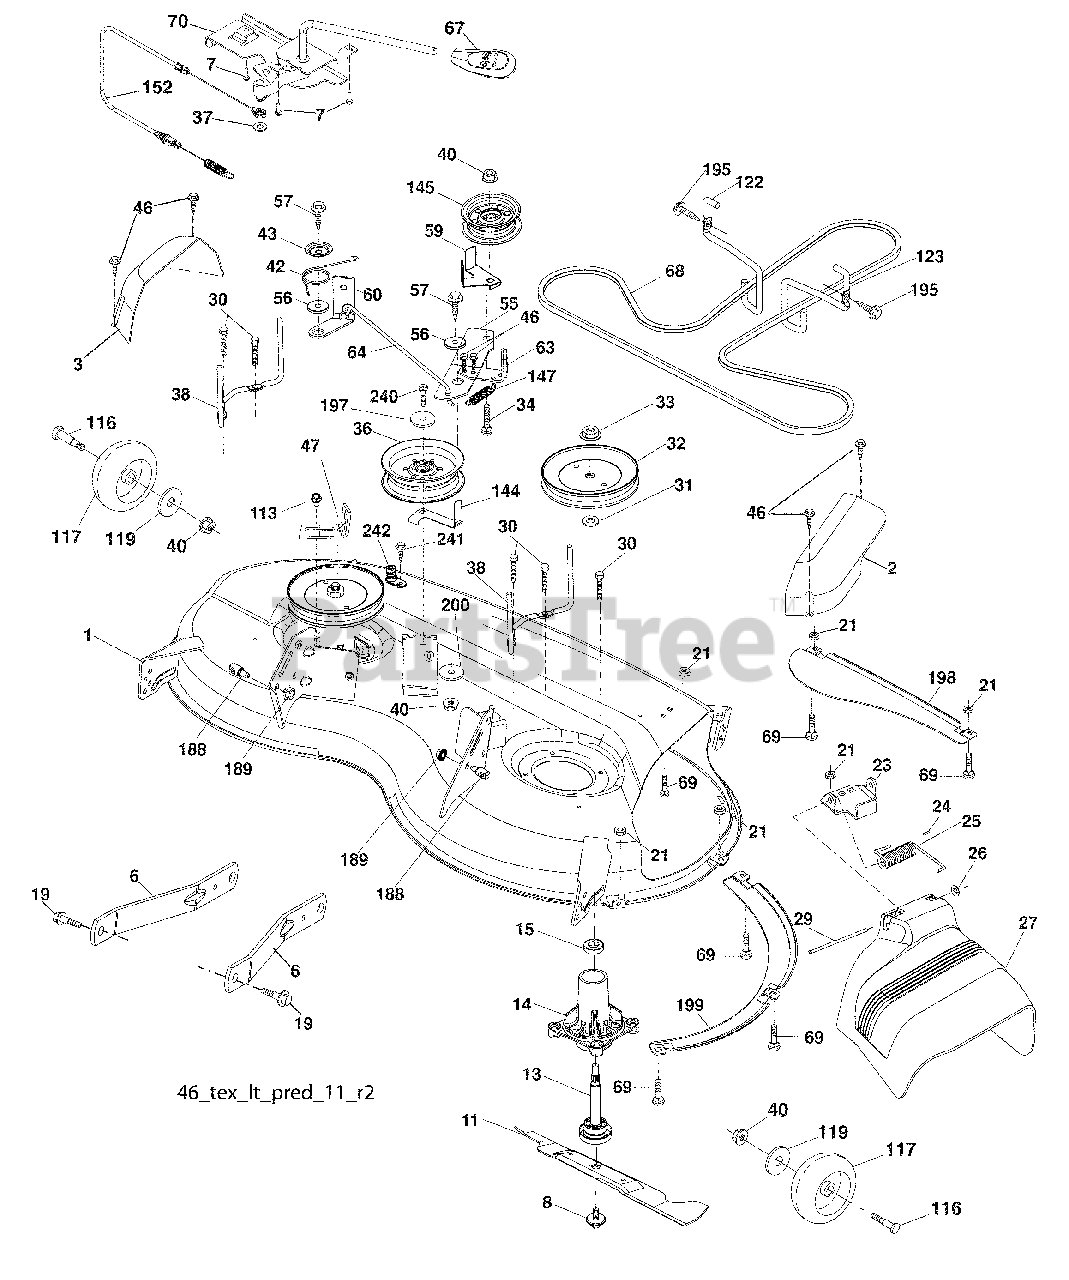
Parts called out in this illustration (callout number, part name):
1	Mower Housing
2	Cover Mandrel RH
3	Cover Mandrel LH
6	Arm Suspension
7	Screw # 10 x 0.750
8	Bolt/Washer asm 7/16-20 unf
11	Blade Mower Hi Lift
13	Shaft Assembly, Mandrel
14	Housing, Mandrel
15	Bearing, Ball, Mandrel
19	Bolt, Shoulder
21	Nut
23	Bracket, Deflector
24	Cap, Sleeve
25	Spring, Torsion, Deflector
27	Shield, Deflector
29	Rod, Hinge
30	Screw Thdrol Rolling Wsh Hd
31	Washer, Spacer
32	Pulley, Mandrel
33	Nut, Toplock, Flanged
34	Bolt Carr Sh. 3/8-16 x 1-1/2 Gr. 5
36	Pulley, Idler, Flat
37	Washer 13/32 x 13/16 x 16 Ga.
38	Keeper Belt LH Mandrel
40	Nut, Lock Flg. 3/8-16 unc
42	Spring Torsion Brake
43	Spring Torsion Retainer
47	Bracket Clutch Cable
55	Arm, Idler
56	Spacer, Retainer
57	Screw Hexwsh Thd 3/8-16 x 1
59	Guard, Tuv Idler (94)
60	Arm Brake Mower LH
63	Arm Brake Mower
64	Linkage Brake
67	Handle, Clutch Cable
68	V-Belt
69	Bolt
70	Clutch Asm. Cable
113	Screw 5/16-18
116	Bolt, Shoulder
117	Wheel, Gauge
119	Washer 13/32 x 1-1/4 x 12 Ga.
122	Keeper Belt Eng. LH
123	Keeper Belt Eng. RH
144	Keeper Belt
145	Pulley Idler
147	Spring Return
152	Cable Clutch Manual w/Spr.
188	Stud Fastener
189	Nut Lock Hex Flange
195	Screw 3/8-16 x 3/4
197	Washer 13/32 x 13/16 x 12 Ga.
198	Baffle Center Front
199	Baffle Front RH
200	Washer 13/32 x 1 x 1/2 11 Ga.
240	Bolt 3/8-16 unc x 2-1/4 Gr. 5
242	Washout Port
